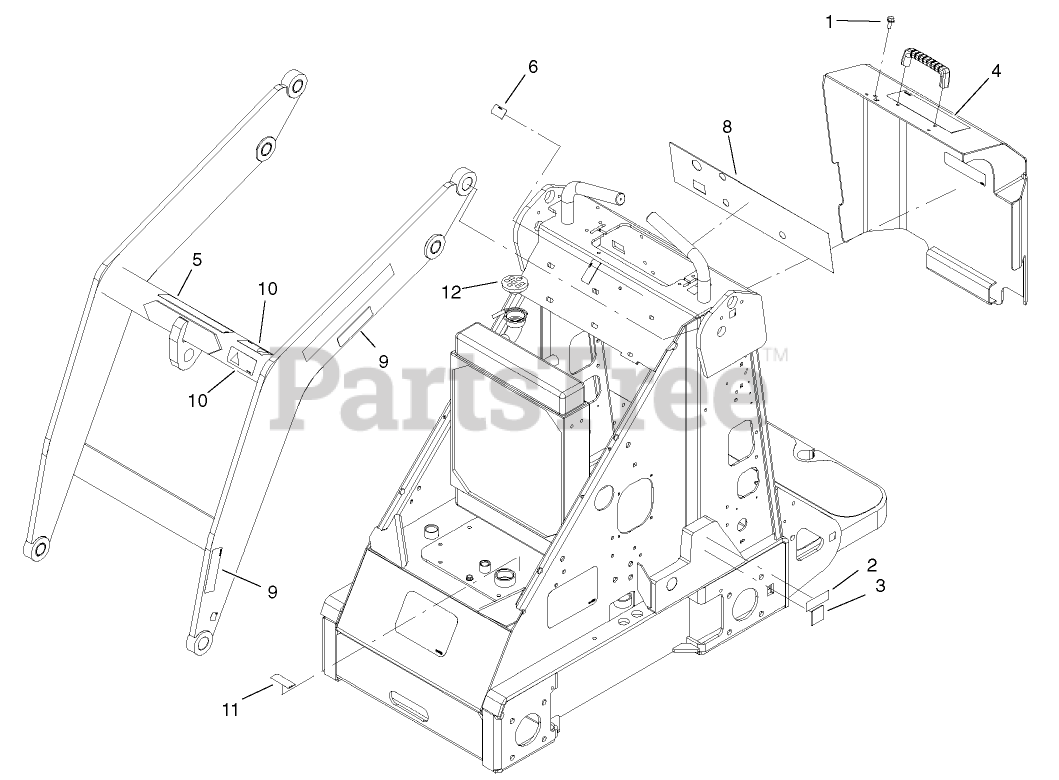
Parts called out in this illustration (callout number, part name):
1	SCREW-HWHTF
2	Decal-Ce
3	DECAL-NOISE, EUROPE
4	DECAL-DANGER
5	DECAL-CAUTION
6	DECAL-LIMITER, SPEED
8	DECAL-PANEL, CONTROL
9	DECAL-WARNING, PINCH
10	DECAL-NO RIDER
11	DECAL-OIL, HYD
12	DECAL-WARNING
